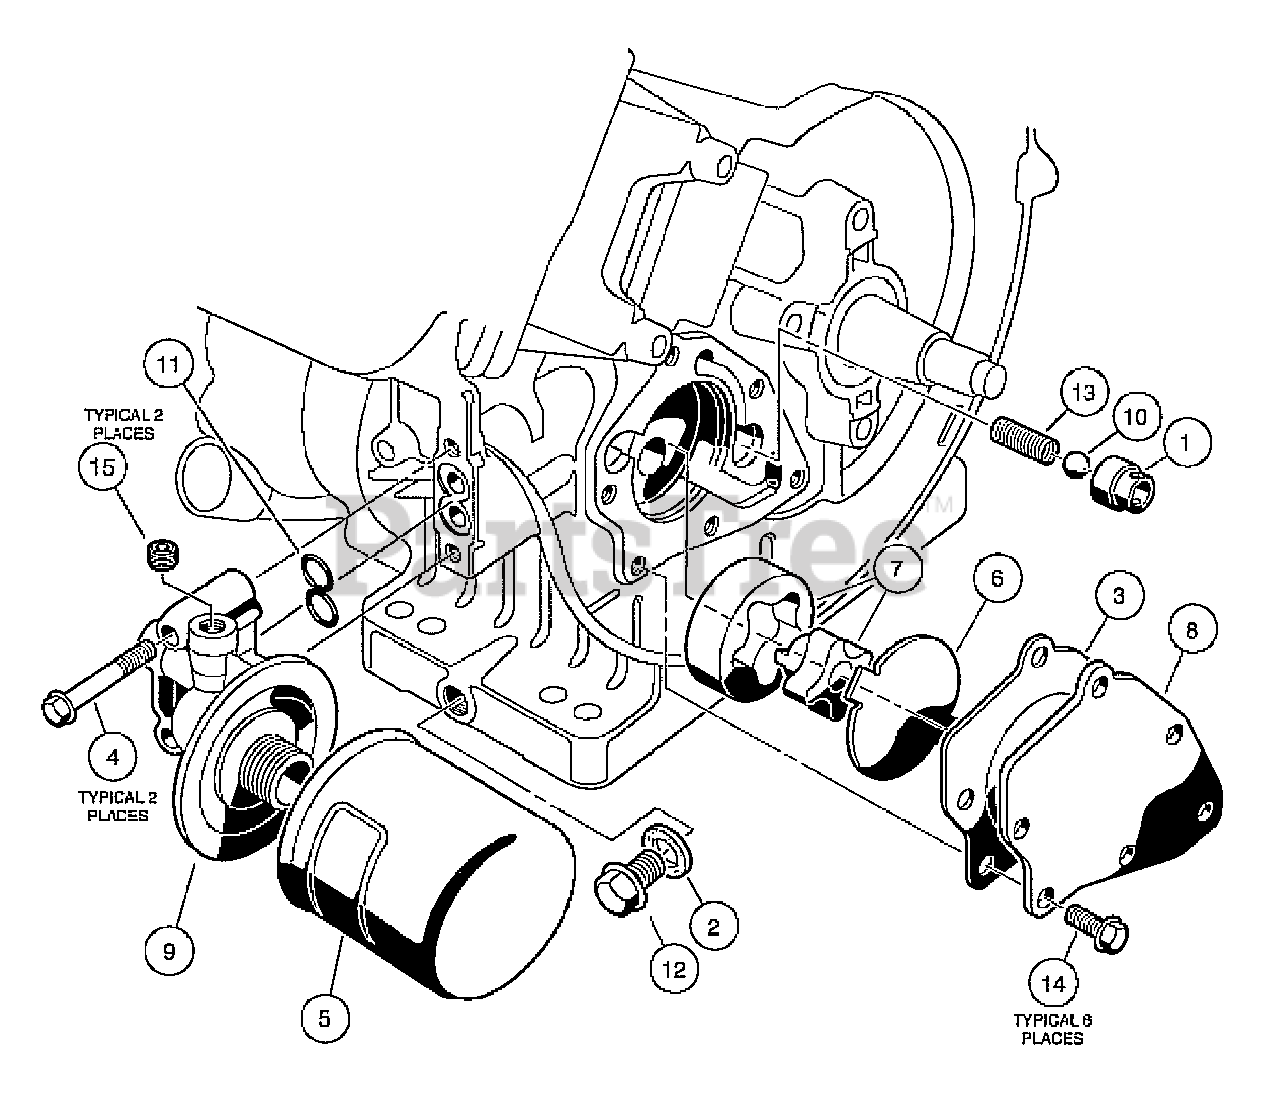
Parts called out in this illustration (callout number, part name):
1	Seat, Value Oil Press Relief
2	Gasket, Drain Plug
3	Gasket, Oil Pump
4	Bolt, Flange Head
5	Filter, Oil
6	Plate, Oil Pump
7	Oil Pump And Rotor
8	Cover, Pump
9	Bracket, Oil Filter Mount
10	Ball, Steel, Press, Relief
12	Plug, Drain
14	Bolt, Flanged
